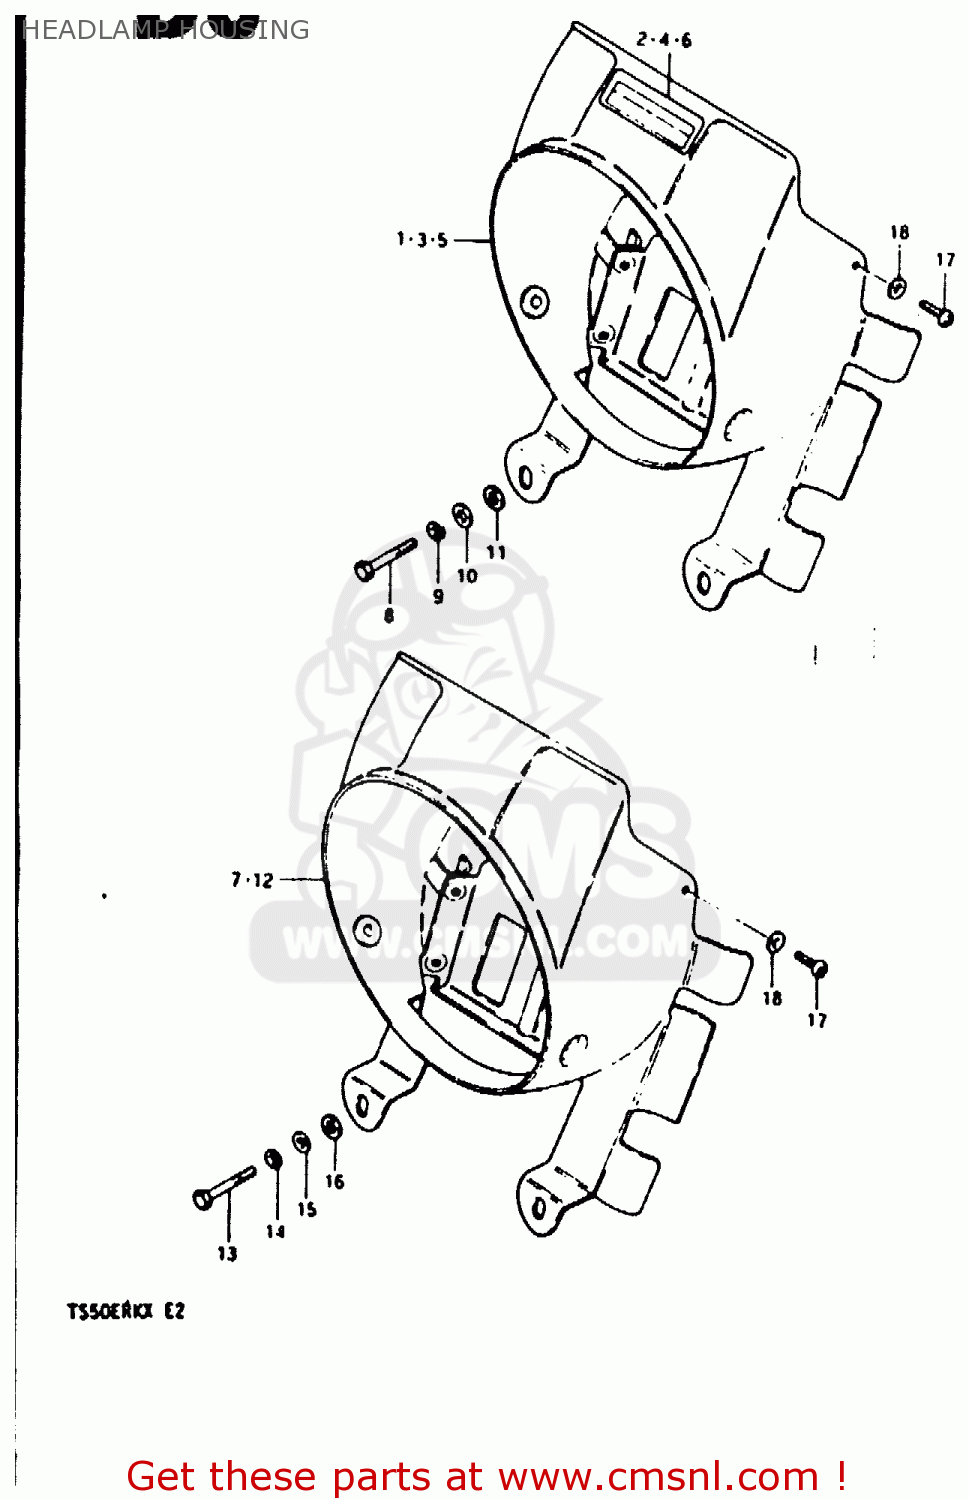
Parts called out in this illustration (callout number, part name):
1	HOUSING, HEADLAMP
2	TAPE, HOUSING
3	HOUSING, HEADLAMP
4	TAPE, HOUSING
5	HOUSING, HEADLAMP
6	TAPE, HOUSING
8	BOLT
9	LOCK WASHER
10	WASHER
11	WASHER
12	HOUSING, HEADLAMP
13	BOLT
14	LOCK WASHER
15	WASHER
16	WASHER
17	SCREW
18	WASHER (5.5X16X1.2)
